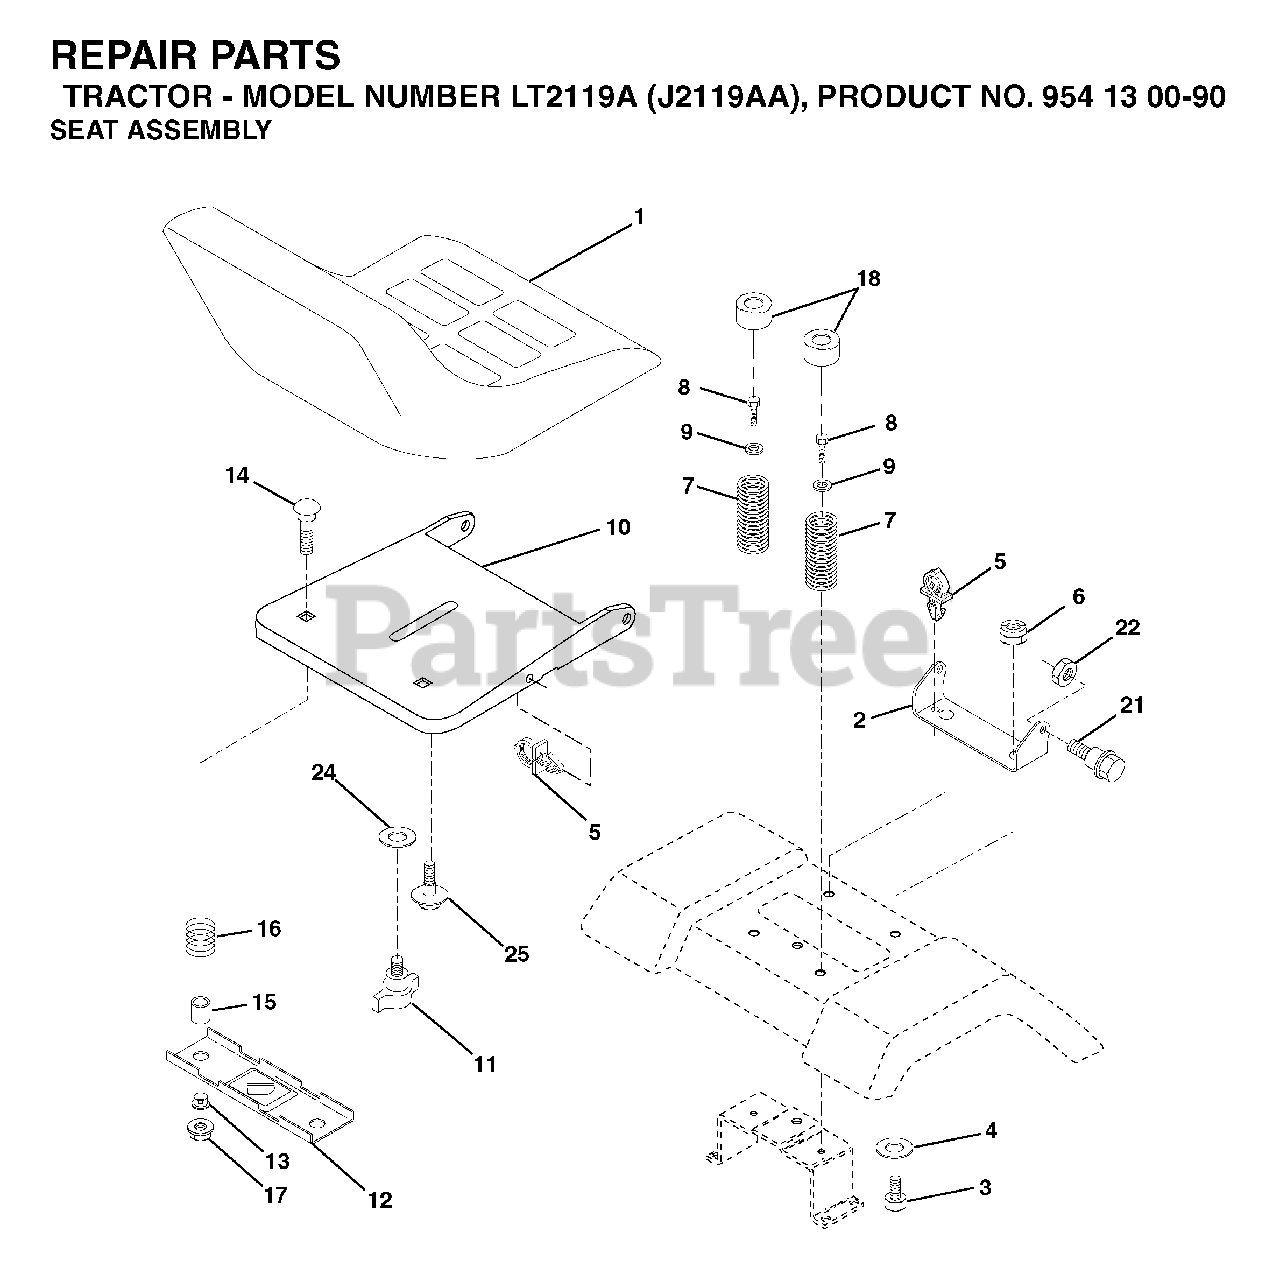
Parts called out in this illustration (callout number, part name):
2	SEAT PIVOT BRKT
4	WASHER PM
5	PUSH CLIP
6	NUT
7	SPRING COMPRESSION
8	SCREW 3/8-16X1
9	WASHER
10	PAN SEAT
11	KNOB.SEAT.ADJ.WINGNUT
12	BRKT SWITCH
14	BOLT.ROUND.HEAD.SQUARE.NECK
15	SPACER SPLIT
16	SPRING COMPRESSED
17	NUT T
18	CAP SPRING
21	BOLT.SHOULDER.5/16-18
22	NUT.71038.31-18.HEX.NYLOCK
25	BOLT,SHOULD
